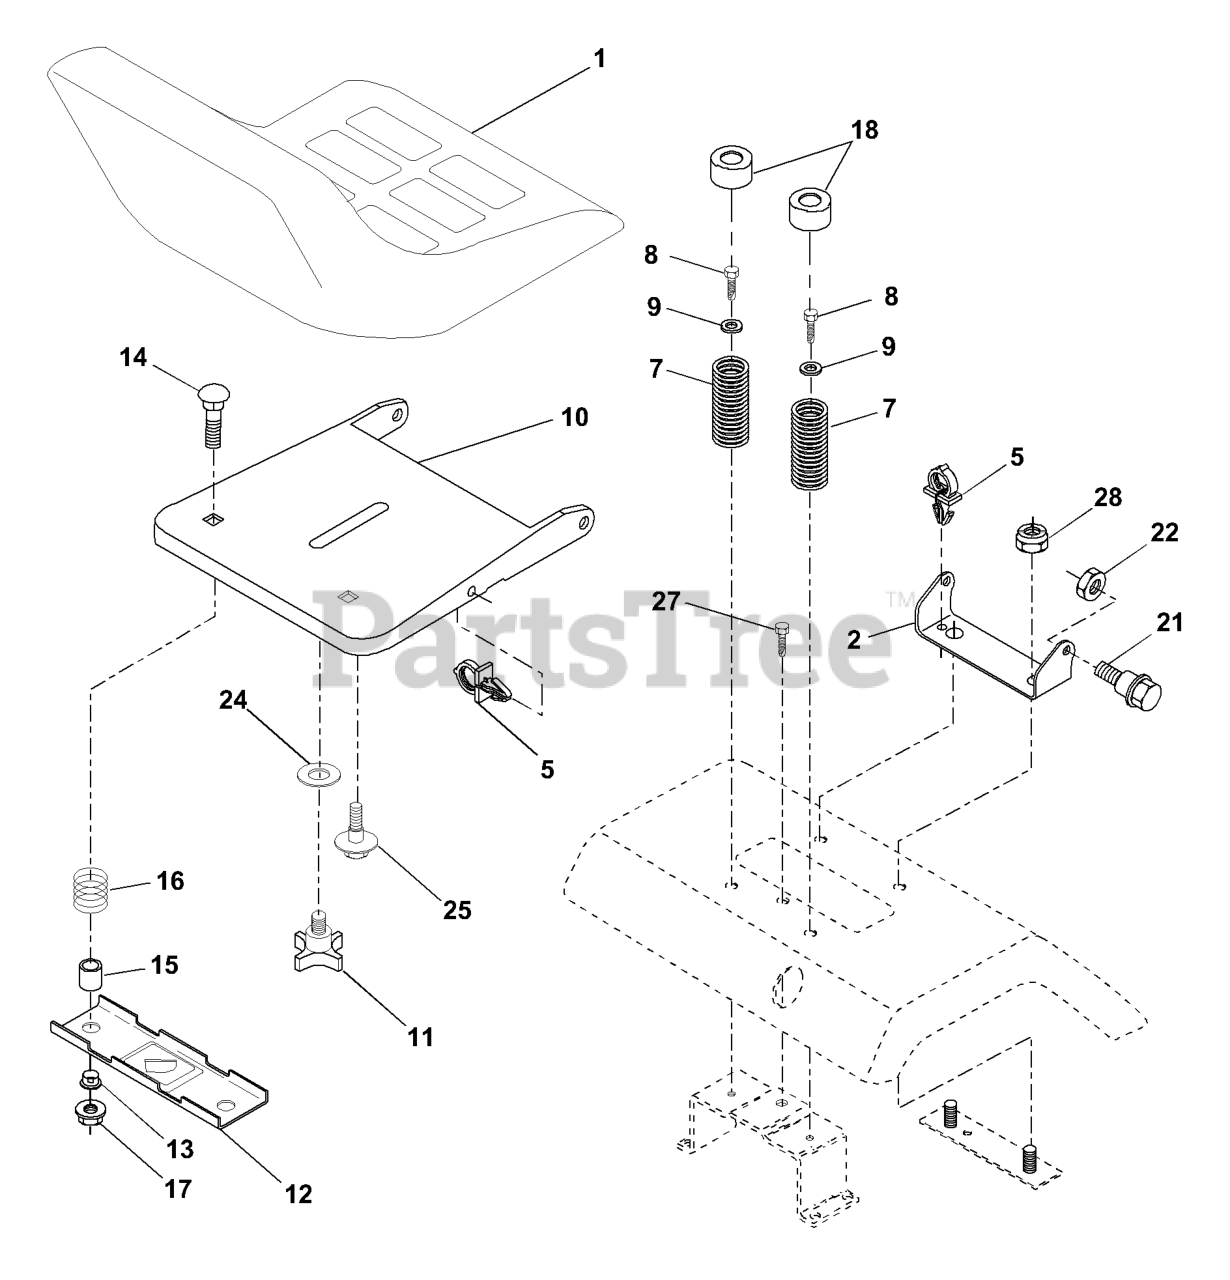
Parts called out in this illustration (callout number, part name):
1	SEAT
2	SEAT PIVOT BRKT
7	SPRING COMPRESSION
8	Screw Hwsh Thdrol 5/16-18 x 1/2
9	WASHER
10	SEAT PAN
11	KNOB 1/2" YT
12	BRKT SWITCH
14	Bolt Rdhd Sht Nk 1/4-20x1-3/8
15	SPACER SPLIT
16	SPRING COMPRESSED
17	NUT T
18	CAP SPRING
21	BOLT.SHOULDER.5/16-18
22	LOCKNUT
25	BOLT,SHOULD
27	SCREW LT
